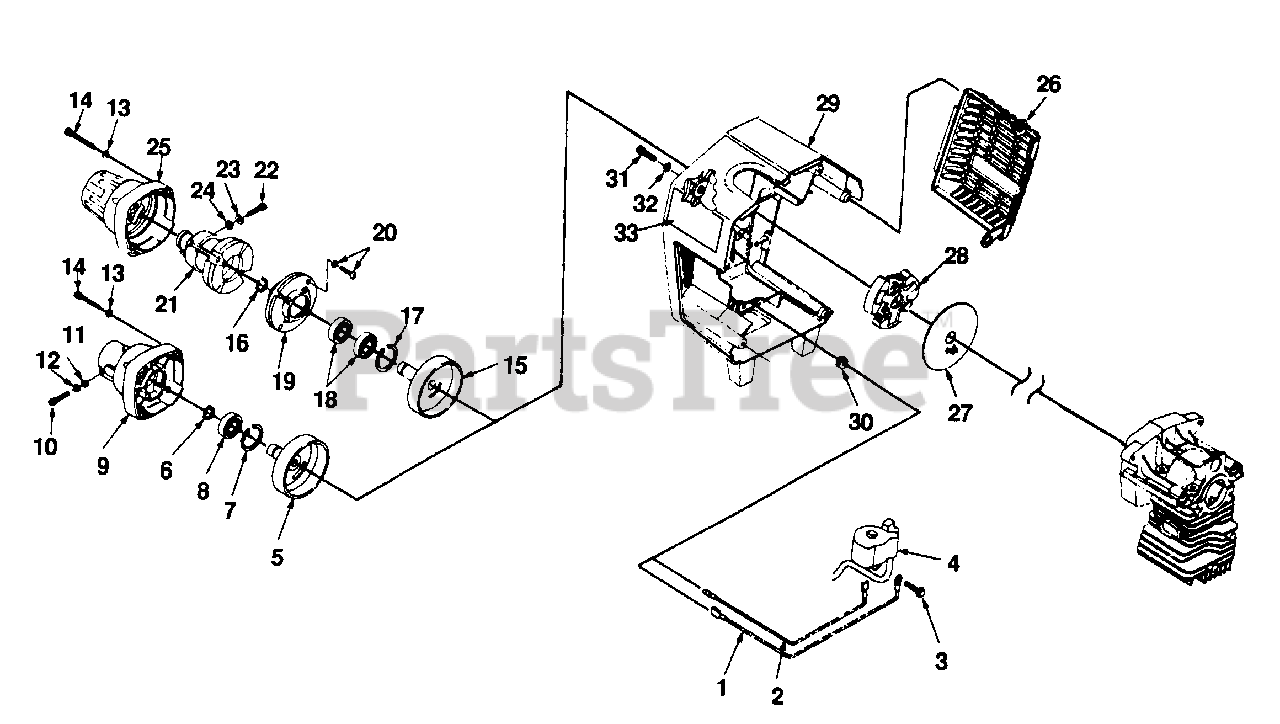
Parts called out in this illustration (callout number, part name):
1	WIRE-Ignition
2	WIRE-Ignition Ground
3	SCREW-Sems Hex Hd. (10-24 X 7/8")
4	MODULE-ignition (Phelon)
5	DRUM-Clutch
6	RING-Snap
7	RING-Snap
8	BEARING-Ball
9	CASE-Clutch
11	WASHER-Plain
13	WASHER-Flat (#12)
14	SCREW-Socket Hd. (12-24 X 1 1/2")
15	DRUM-Clutch
16	RING-Snap
17	RING-Snap
18	BEARING-Ball
19	COVER-Clutch
21	INSERT RING ASSEMBLY
25	CLUTCH CASE
26	SHIELD-Muffler (Flocked)
27	PLUG-Crankcase
29	SHROUD
30	GROMMET
31	SCREW-Socket Hd. (12-24 X 3/4")
32	WASHER-Flat (#12)
33	DECAL-Conformity
